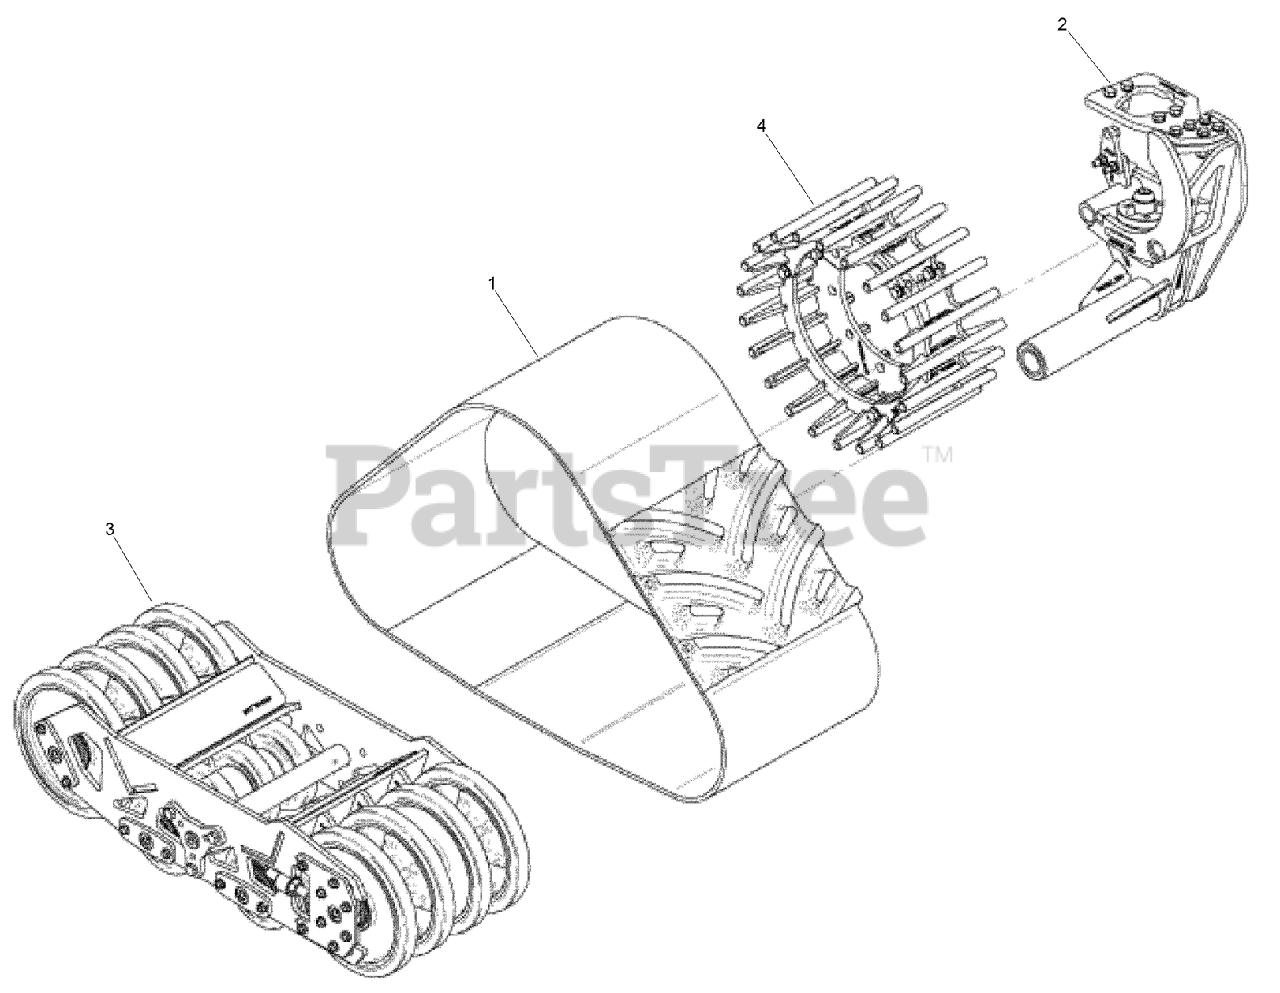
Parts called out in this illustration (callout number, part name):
1	TRACK-RUBBER, 511E, 19.5 IN
2	ASSEMBLY - Track Mounting Structure, Front Right / Rear Left
3	ASSEMBLY - Track Chassis
4	ASSEMBLY - Track Sprocket
